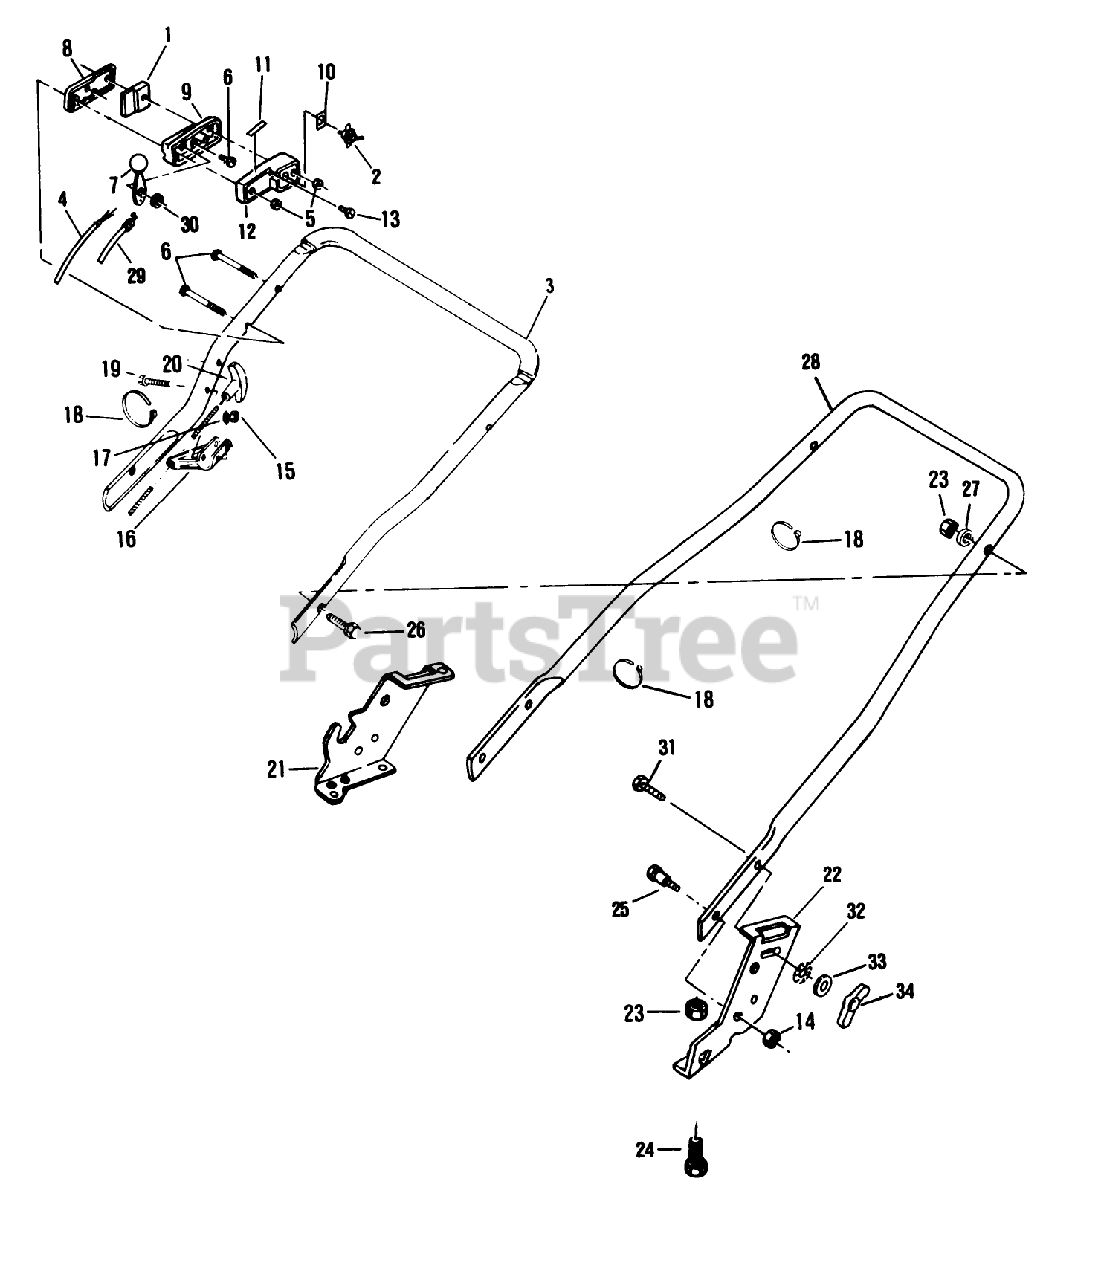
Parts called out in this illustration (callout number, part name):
5	NUT C/LOCK E
6	SCREW
7	LEVER&KNOB AY WES
8	OUTER CONTROL CASE
13	SCREW
14	NUT-JAM, LOCKING
15	LOCKNUT E
17	WASHER
23	NUT-LOCK F
25	BOLT
27	WASHER-CURVED
29	CABLE THROT WES
30	WASHER-SPRING
32	LOCK WASHER LARSON
33	WASHER
34	NUT-WING
